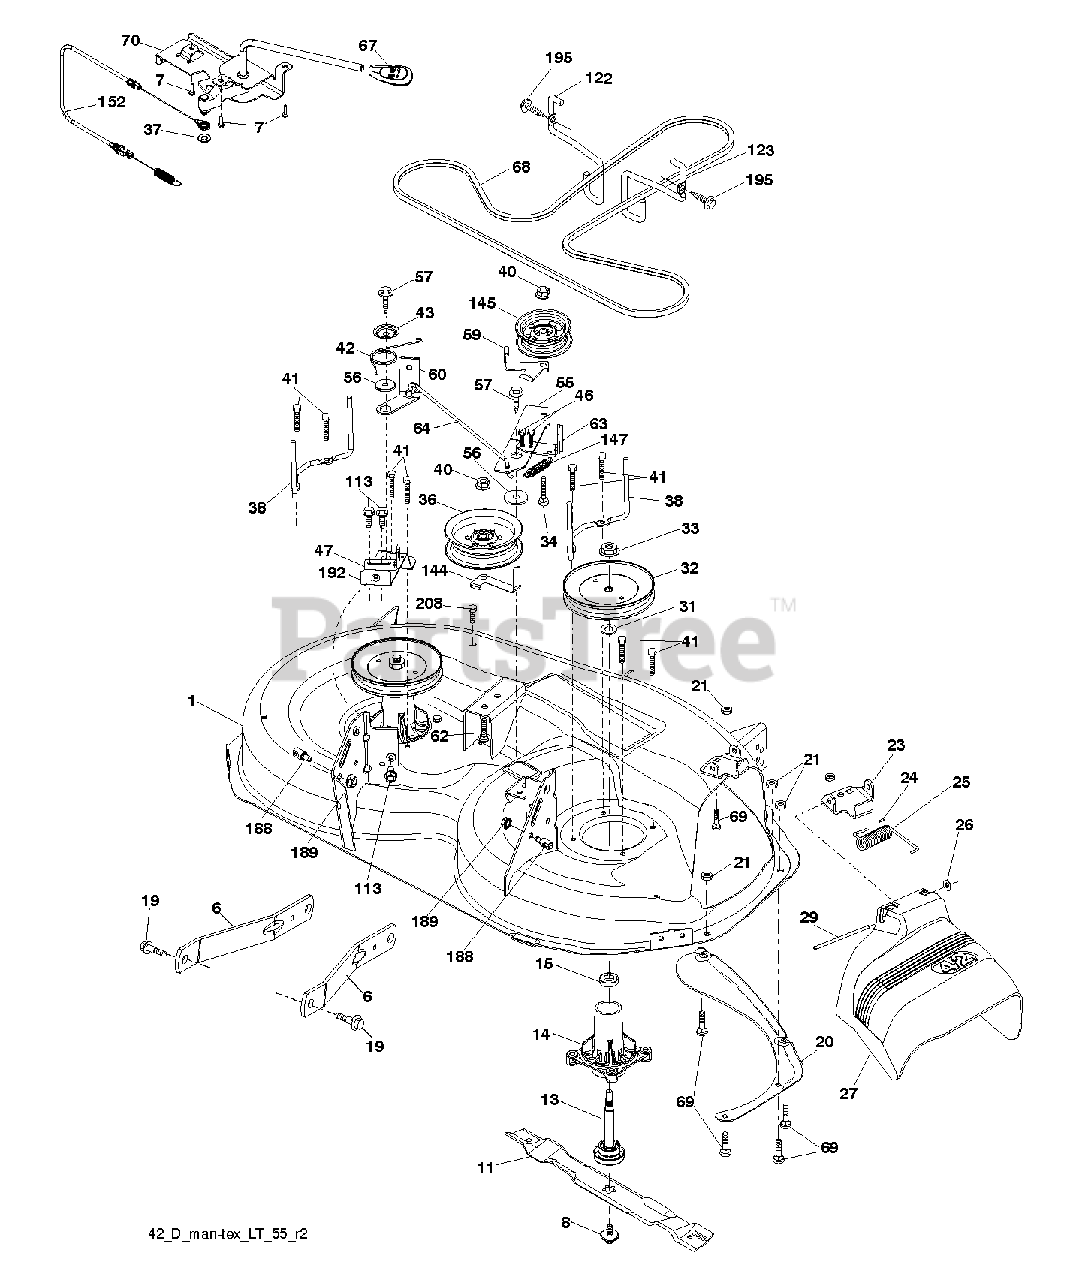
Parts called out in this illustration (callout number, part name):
6	ARM.SUSPENSION.MOWER.R
7	SCREW.#10 X 0.750.BOS (2 2)
8	BOLT.WASHER.ASM.7/16-2
11	42" HI-LIFT BLADE
13	SHAFT.ASM.MDRL.N/GREASE.38
14	HOUSING.MANDREL.4PT.
19	BOLT.SHOULDER
20	BAFFLE.VORTEX
21	LOCKNUT
23	BRKT.DEFLECTOR.38"2005+
24	CAP-SLEEVE LT
25	SPRING.TORSION.DEFLECT
26	NUT PUSH M
27	SHIELD.DEFLECTOR.MOWER.42"BLAC
29	ROD.HINGE
31	WASHER.SPACER.MANDREL
32	PULLEY.MANDREL.5.438.PD
33	NUT.FLANGE.LOCK.TOP
34	BOLT.3/8-16X1.50
36	PULLEY.IDLER.2006
38	KEEPER.BELT.MANDREL.PULLEY
40	NUT LOCK FLG 3/8-16 UNC
41	Hex Washer Head Bolt, .313-18 X 1.19
42	SPRING.TORSION.BRAKE
43	SRPING.TORSION.RETAINE
46	SCREW.1/4-20X5/8
47	BRKT.CLUTCH.CABLE
55	IDLER.ARM.42"
56	SPACER.RETAINER
57	SCREW 3/8-16X1
59	GUARD, BELT
60	ARM BRAKE MOWER
62	BOLT
64	LINK BRAKE
67	HANDLE.CLUTCH.CABLE.LT
68	BELT.DECK.DRIVE.42"
69	BOLT
70	CLUTCH.ASM.MANUAL.LT.TEX
113	BOLT.5/16HEX.WHS.HD
122	KEEPER BELT ENGINE LH
123	KEEPER BELT RH
144	KEEPER.BELT.MOWER
145	PULLEY.IDLER.48"PRIMARY
147	RETURN SPRING
152	CABLE.MECHANICAL.CLUTCH
188	STUD.FASTNER.W/ANTI-ROTATE
189	NUT LOCK HEX FLANGE 5/16-18
192	BRKT.BRAKE.STAND.LH.
195	SCREW, 3/8-16X3/4
208	SCREW 3/8-16X1/2
